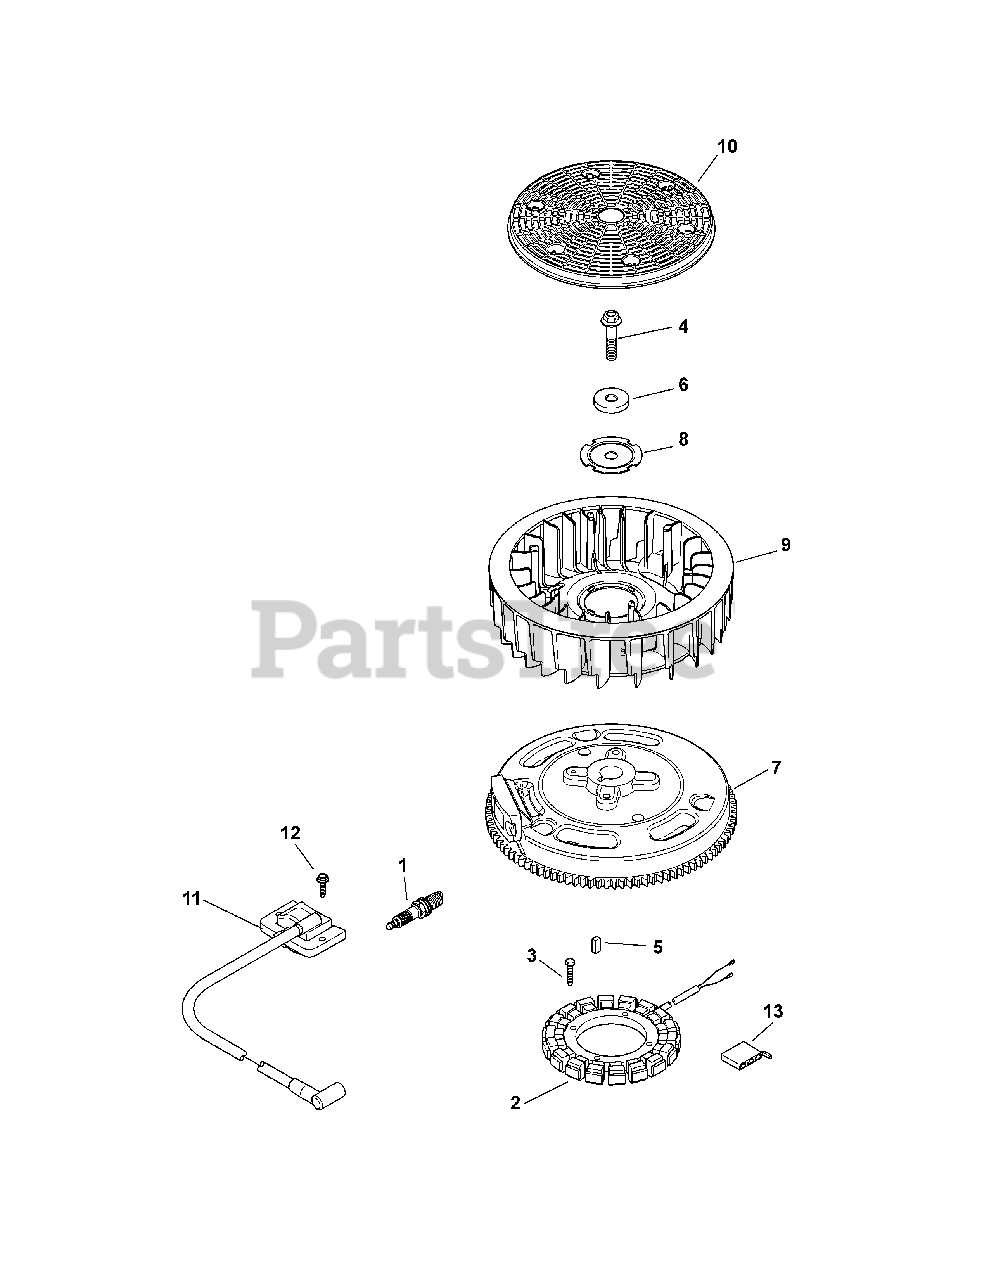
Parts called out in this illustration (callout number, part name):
1	Spark Plug
2	15 Amp Stator Kit (Inc. KH-25-452-01-S)
3	Screw, M5 x 0.8 x 25
4	Hex Flange Screw
7	Flywheel Assembly
8	Fan Mounting Plate
9	Fan
11	Module Ignition Kit
12	Flange Screw, M5 x .8 x 20
